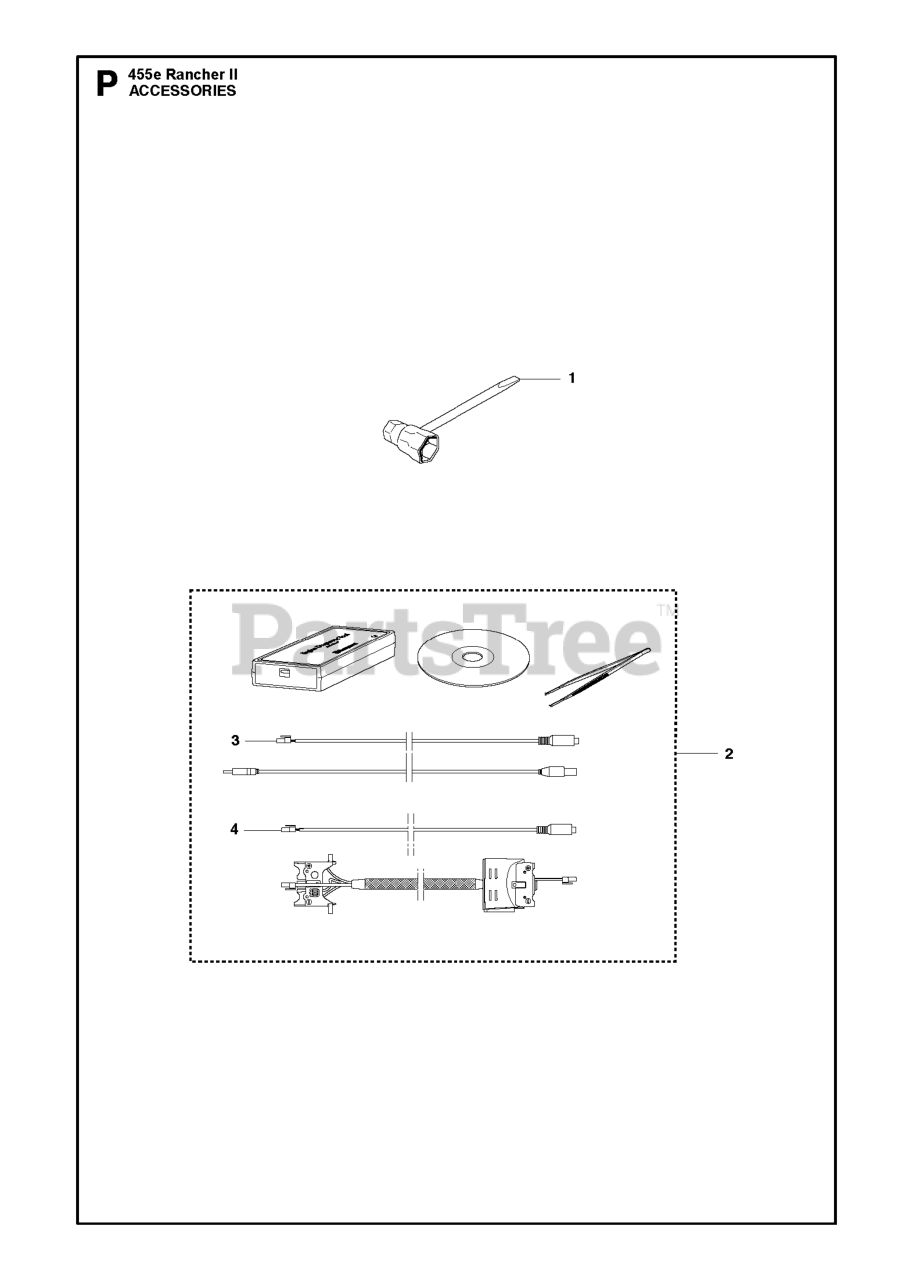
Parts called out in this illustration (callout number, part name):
1	COMBI TOOL
2	DIAGNOSTIC TOOL KIT
3	CABLE ASSY
4	CABLE ASSY
